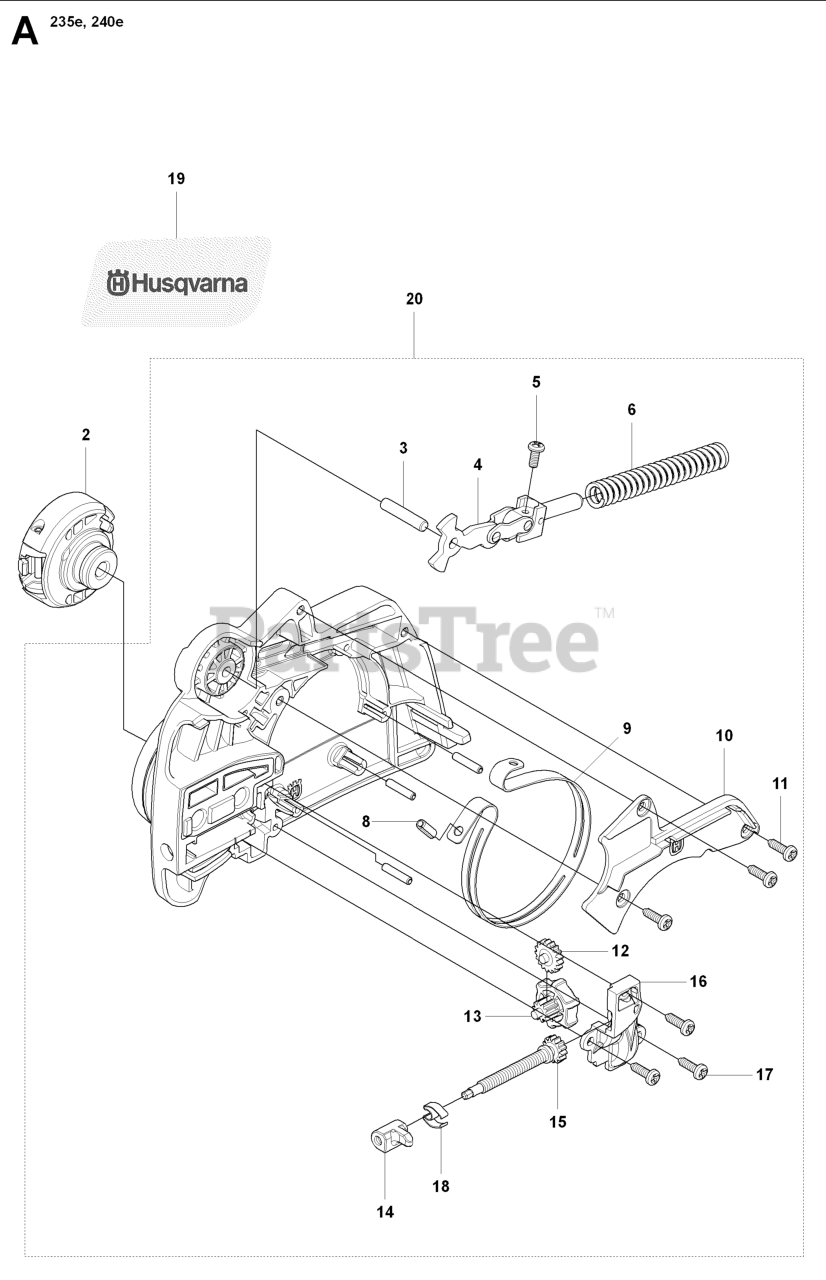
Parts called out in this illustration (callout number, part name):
2	ASSEMBLY KNOB EZT
4	FRONT LINK ASSY
5	SCREW
9	BRAKE BAND
10	COVER, BRAKE BAND
11	SCREW
12	GEAR IDLER
13	WHEEL, GEAR ADUSTER
14	PIN BAR ADJUSTING
16	COVER, GEAR
17	SCREW
19	DECAL, EZT CLUTCH
20	CHAIN BRAKE ASSY
